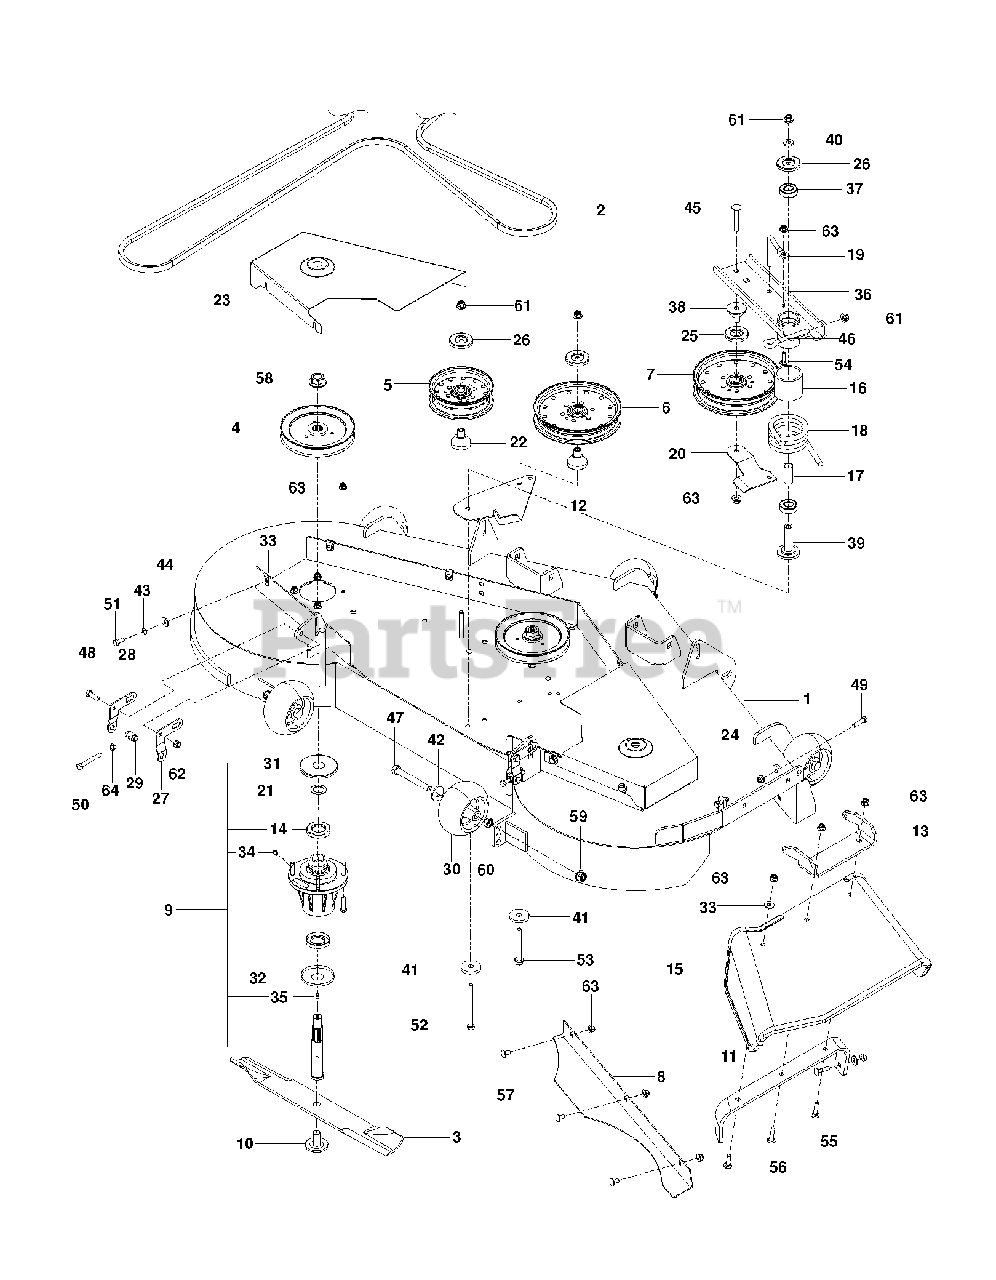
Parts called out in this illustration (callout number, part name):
1	DECK W/DECALS DX148
2	BELT DECK DX148
4	PULLEY 42-48
5	IDLER PULLEY
6	PULLEY - 7" NARROW
7	PULLEY - IDLER 7"
8	CONFINEMENT PLATE 61
10	BLADE BOLT/WASHER
11	BRKT, REINF - CHUTE 52/61"
12	BRACKET, SPRING STOP
13	PIVOT BRACKET - CHUTE
15	SPACER, IDLER BEARINGS
18	BELT GUIDE, BLK
19	MACHINE BUSHING
20	BELT GUIDE, BLK
21	BELTSHIELD - L.H. BLUE
22	BELTSHIELD - R.H. BLUE
23	SHIELD, DUST
24	DUST SHIELD
25	PITCH, ADJUST, LT
26	PITCH, ADJUST, RT
27	TRUNION, PITCH
29	TOP DUST CAP
30	BOTTOM DUST CAP
31	PLUG-VENTED
33	IDLER.ARM.BLACK
34	CHUTE DISCHARGE 48"
35	BEARING, IDLER ARM
36	BEARING, IDLER PIVOT
37	BEARING, BALL
38	SHAFT SEAL
39	U-CLIP 5/16-18 NUT RETAINER
40	CARRIAGE BOLT 3/8-16 X
43	HCS 1/2-13 X 4 GR 5 ZD
44	HCS 3/8C X 1
45	HCS 5/16C X 1 1/4
46	HCS 5/16-18 X 2 1/2 TPBLT
47	HCS 5/16C X 3/4
48	HCS 3/8-16 X 4-1/2 GR 8 ZD
49	CARRIAGE BOLT 5/16C X 5/8"
50	RHSSNB 5/16C X 1.0
51	RHSNB 5/16-18 X 1-1/2 GR 5 ZD
52	BOLT, CARRIAGE 5/16X1-1/4
53	NUT 5/16C HEX
54	NUT FLANGE 3/4-16
55	NUT, 1/2-13 HEX FLG NYLOC ZD
56	NUT 1/2 HEX JAM
57	NUT 3/8-16 HEX FLG NYLOC ZD
58	NUT 3/8-16 NYLOC
59	5/16-18 NYLOC FLANGE NUT
60	SPINDLE WASHER
61	WASH USS FLAT 1/2
62	WASH 5/16 DISC SPRING ZD
63	WASHER 5/16 FLAT
64	WASHER, 3/8 THICK
